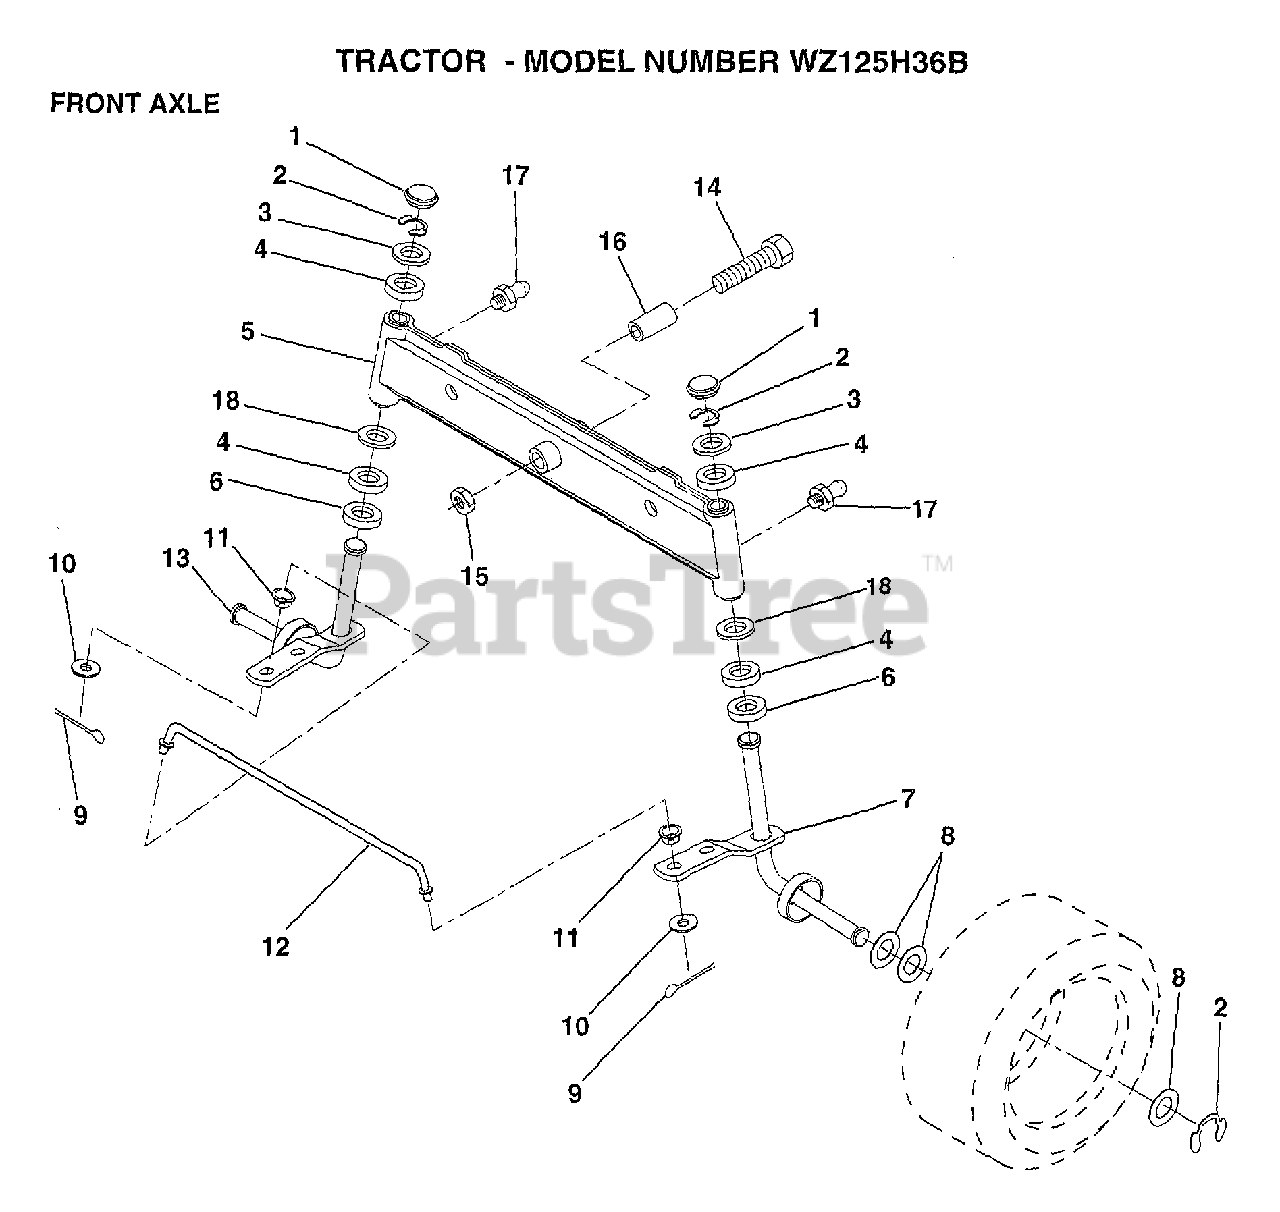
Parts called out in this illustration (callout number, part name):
1	CAP
2	RING
3	WASHER
4	COL. SRTG. BEAR.
5	AXLE ASM FRONT
6	WASHER .T
7	SPINDLE.ASSY.RH
8	WASHER
9	COTTER PIN
10	WASHER
11	BUSHING.DRAGLINK
12	TIE ROD
13	SPINDLE.ASSY.LH
14	BOLT HEX 5/8-11
15	"NUT-LOC,FLANGE LT"
16	BEARING
17	ZERK M
18	WASHER
